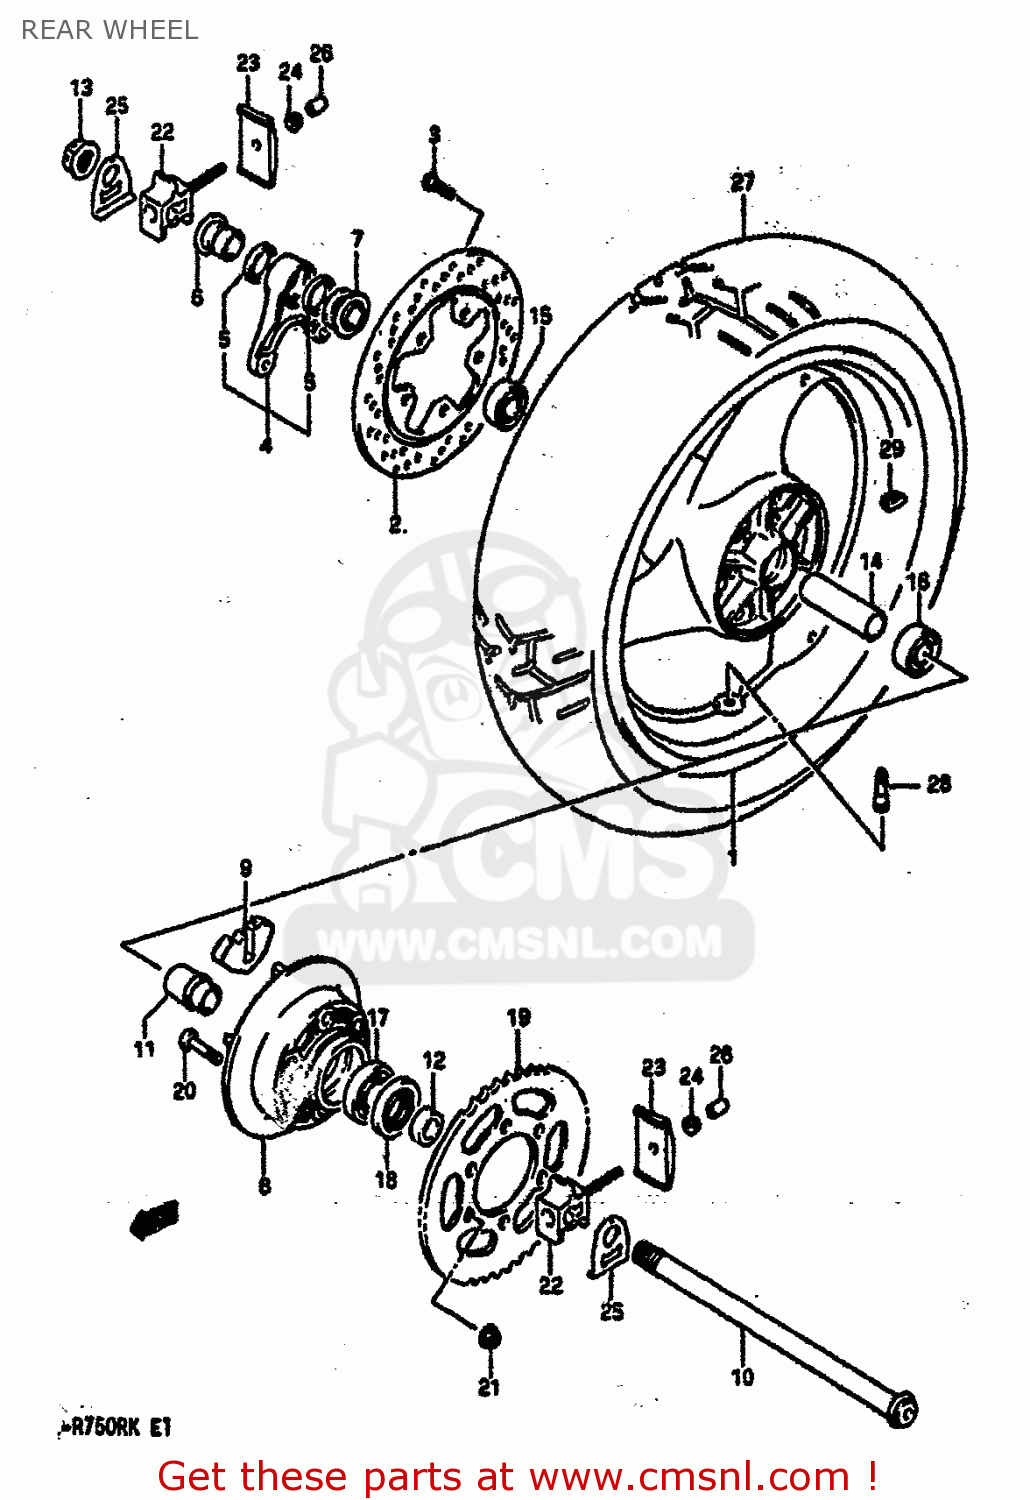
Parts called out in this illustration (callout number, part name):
1	WHEEL,RR(17XMT5.50)
2	DISC,RR BRAKE
3	BOLT
4	BRACKET,RR CALIPER
5	SEAL,OIL(28X35X5)
6	SPACER,RR CALIPER BRACKET
7	SPACER,RR AXLE,R
8	DRUM,RR SPROCKET MOUNTING
9	ABSORBER,RR HUB SHOCK
10	AXLE,RR
11	RETAINER,RR HUB BEARING
12	SPACER,RR AXLE,L
13	NUT
14	SPACER,RR WHEEL HUB BEARING
15	BEARING
16	BEARING(20X47X14)
17	BEARING(25X62X17)
18	SEAL,OIL(35X62X8)
19	SPROCKET,REAR (NT:39)
20	BOLT
21	NUT
22	ADJUSTER,CHAIN
23	PLATE,CHAIN ADJUSTER GEAR
24	NUT
25	WASHER,CHAIN ADJUSTER(D=20)
26	CAP,CHAIN ADJUSTER
27	TIRE
28	VALVE ASSY,WHEEL RIM(TR412)
29	BALANCER,WHEEL
